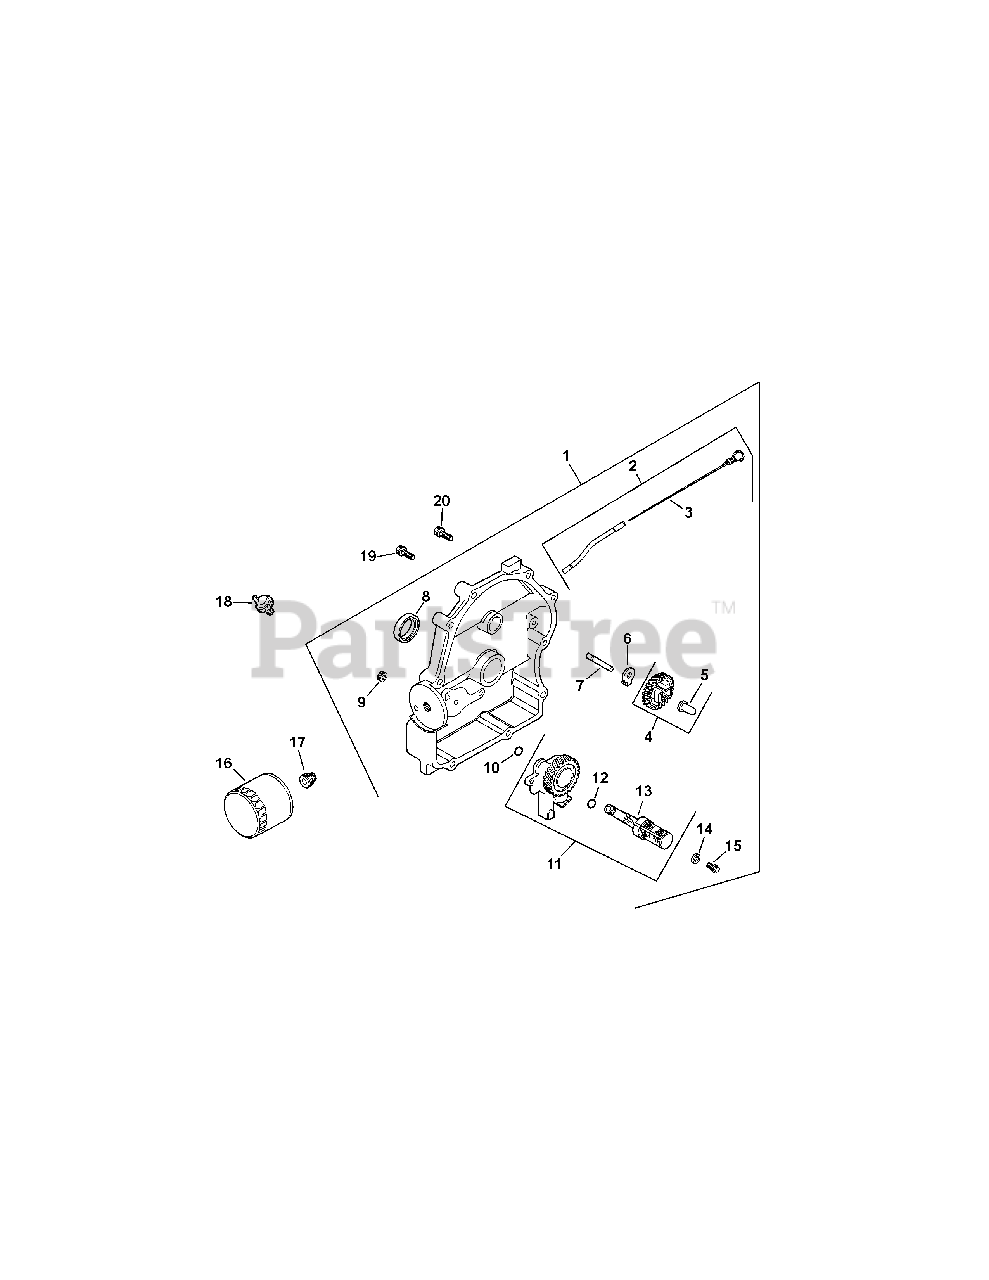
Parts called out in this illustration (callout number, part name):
1	Plate, closure ass’y (Incl. 2-15)
2	Kit, tube w/dipstick (Includes 3)
4	Kit, governor gear (Includes 5)
5	Pin, governor regulating
7	Shaft, governor gear
8	Seal, oil (PTO end)
9	Plug, pipe 1/8" (2)
11	Oil pump ass’y (Includes 12,13)
12	O-Ring, oil pick-up
13	Pick-up, oil
14	Washer, plain 6 mm (2)
15	Screw, hex flange M6x1.0x25 (2)
17	Nipple, oil filter
18	Switch, pressure
19	Screw, hex flg, M8x1.25x45 (9)
20	Screw, hex. flange M8x1.25x45
